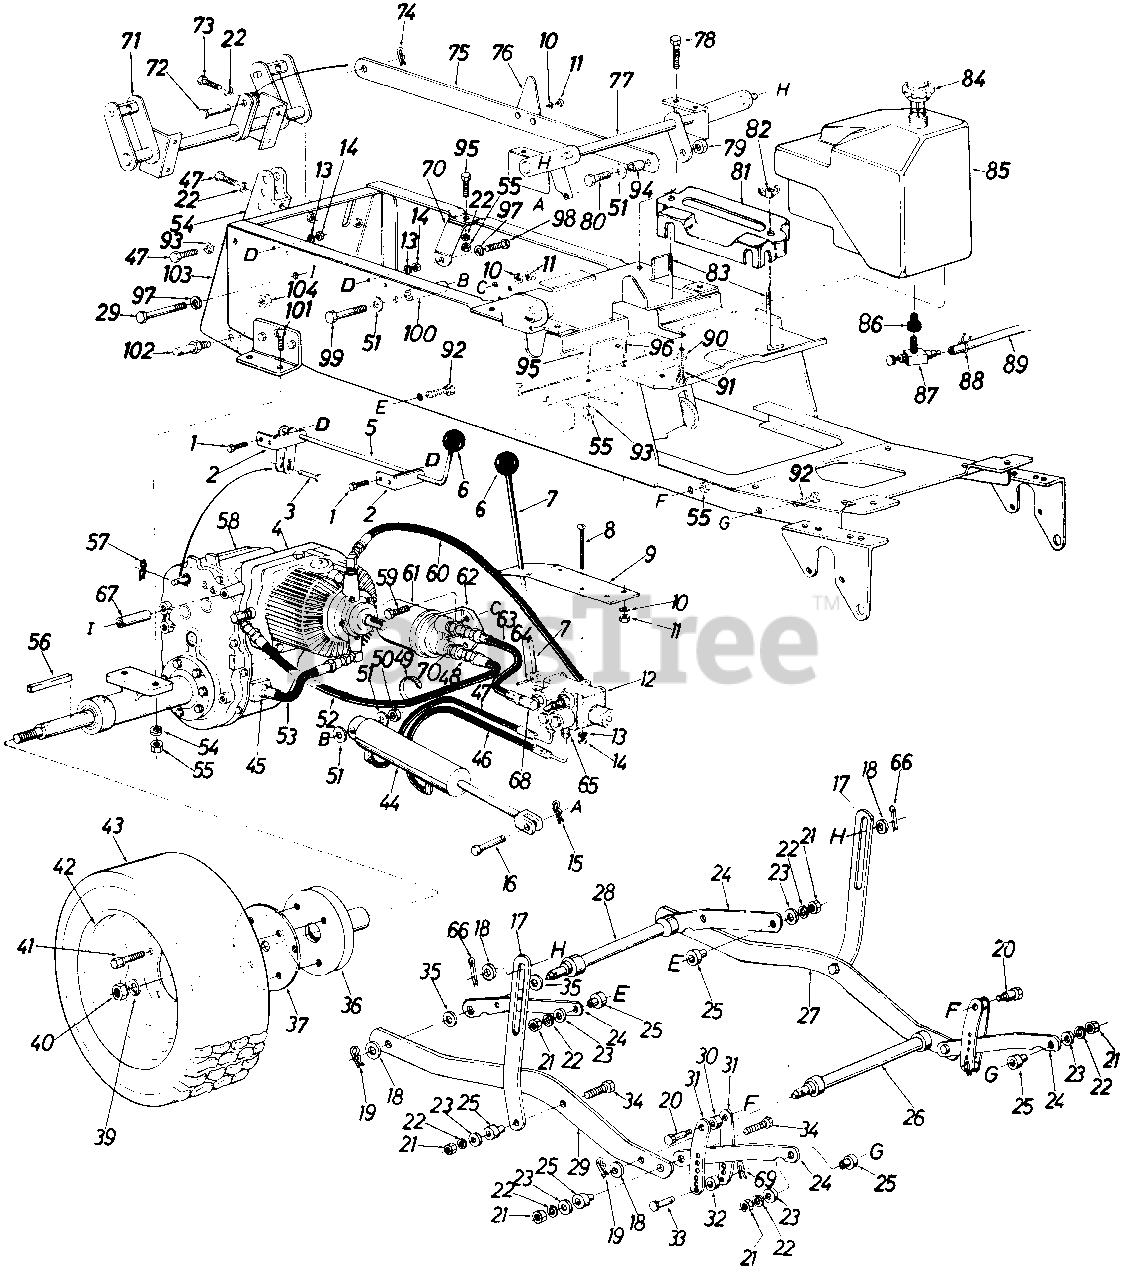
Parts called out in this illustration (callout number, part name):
1	Hex Bolt 1/4-20 x .75" Lg.
4	Hydrostatic Pump Comp.
5	Hi-Lo Control Handle Ass'y.
6	Ball Knob
7	Cylinder Control Handle Ass'y.
8	Truss Mach. Scr. 1/4-20 x 3.00" Lg.
11	Hex Nut 5/16-18 Thd.
12	IValve Ass'y. Comp.
13	L-Wash 1/4 " I . D .
14	Hex Nut '/4-20 Thd.
15	Hairpin Cotter 1/2" Dia.
16	Clevis Pin '/2" Dia.
19	Hairpin Cotter
20	Shld. Bolt .498 Dia. x .66
21	Hex Nut 3/8-24 Thd.
22	L-Wash. 3/8" I.D. H.D.
23	Fl-Wash. .38 I.D. x 1.00"
26	Cross Shaft Ass'y. Front
29	Hex Bolt '/2-13 x 2.75"
30	Collar .50" I.D. x 1.0"
33	Clevis Pin 3/8" Dia.
34	Hex Bolt 3/8-24 x 1.50" Lg. Grade 5
35	Fl-Wash. .62" I.D. x 1.25"
39	L-Wash. 3/4" I.D.
40	Hex Ins. L-Nut 3/4-16 Thd.
41	Wheel Lug Bolt
44	Hydraulic Cylinder
45	7/8-14 UNF-2A 0 Thd. 5/8 Tube Fitting
46	Valve to Cylinder Hose 20"
47	Hex Bolt 3/8-16 x .75" Lg. Grade 5
48	Bushing Reducer 1/2-14 NPTF to 3/8-18 NPTF
49	Cable Tie
50	Hex Jam Nut '/2-20 Thd.
51	Fl-Wash. .50" I.D. x 1.25
52	Filter Return Hose 24" Lg.
53	Pump Tube Ass'y.
55	Hex Nut 3/8-16 Thd.
56	Sq. Key 1/4" X 1/4" X 2"
57	Hairpin Cotter 1/4" Dia.
58	Peerless Transaxle
59	Hex Bolt 5/16-18 x 1.25"
60	Pump to Valve Hose
61	Fram Filter Ass'y. PH-16
63	Valve to Filter Hose 8.38"
64	Spring Pin Spiral 1/8" Dia.
65	Flare Adapter
66	Cotter Pin 1/8" Dia. x 1.0"
68	Adapter 9/16-18 to 9/16-18
69	Hairpin Cotter
70	Transmission Brace
73	Hex Scr. 3/8-16 x 1.00" Lg. Grade 5
74	Cotter Pin 1/8" Dia. x 1.25"
79	Hex Cent. L-Nut 1/2-20 Thd.
80	Hex Scr. 1/2-20 X 1.25" Lg.
81	Battery Cover
82	Wing Nut 1/4-20 Thd.
83	Battery Hold Down Rods
84	Gas Tank Cap
85	Gas Tank Ass'y.
86	Bushing
87	Fuel Shut-Off Valve with Screen
88	Gas Line Clamp 7/16"
89	Gas Line 30" Lg.
91	Hex Scr. 1/4-20 x .38" Lg.
92	Hex Scr. 3/8-24 x 1.50" Lg.
93	L-Wash. 318" Scr.
94	Push Bar Sleeve
95	Hex Scr. 3/8-16 x 1.00 Lg. Grade 5
96	Hex Scr. 5/16-18 x .75" Lg.*
97	L-Wash. '/2" Scr.
98	Hex Scr. 1/2-13 x 1.25" Lg.
99	Hex Scr. '/2-20 x 3'/2" Lg. Grade 5
100	Spacer for Cylinder
101	Hex Scr. 3/8-16 x 1.75" Lg.
102	Link Clevis Pin
